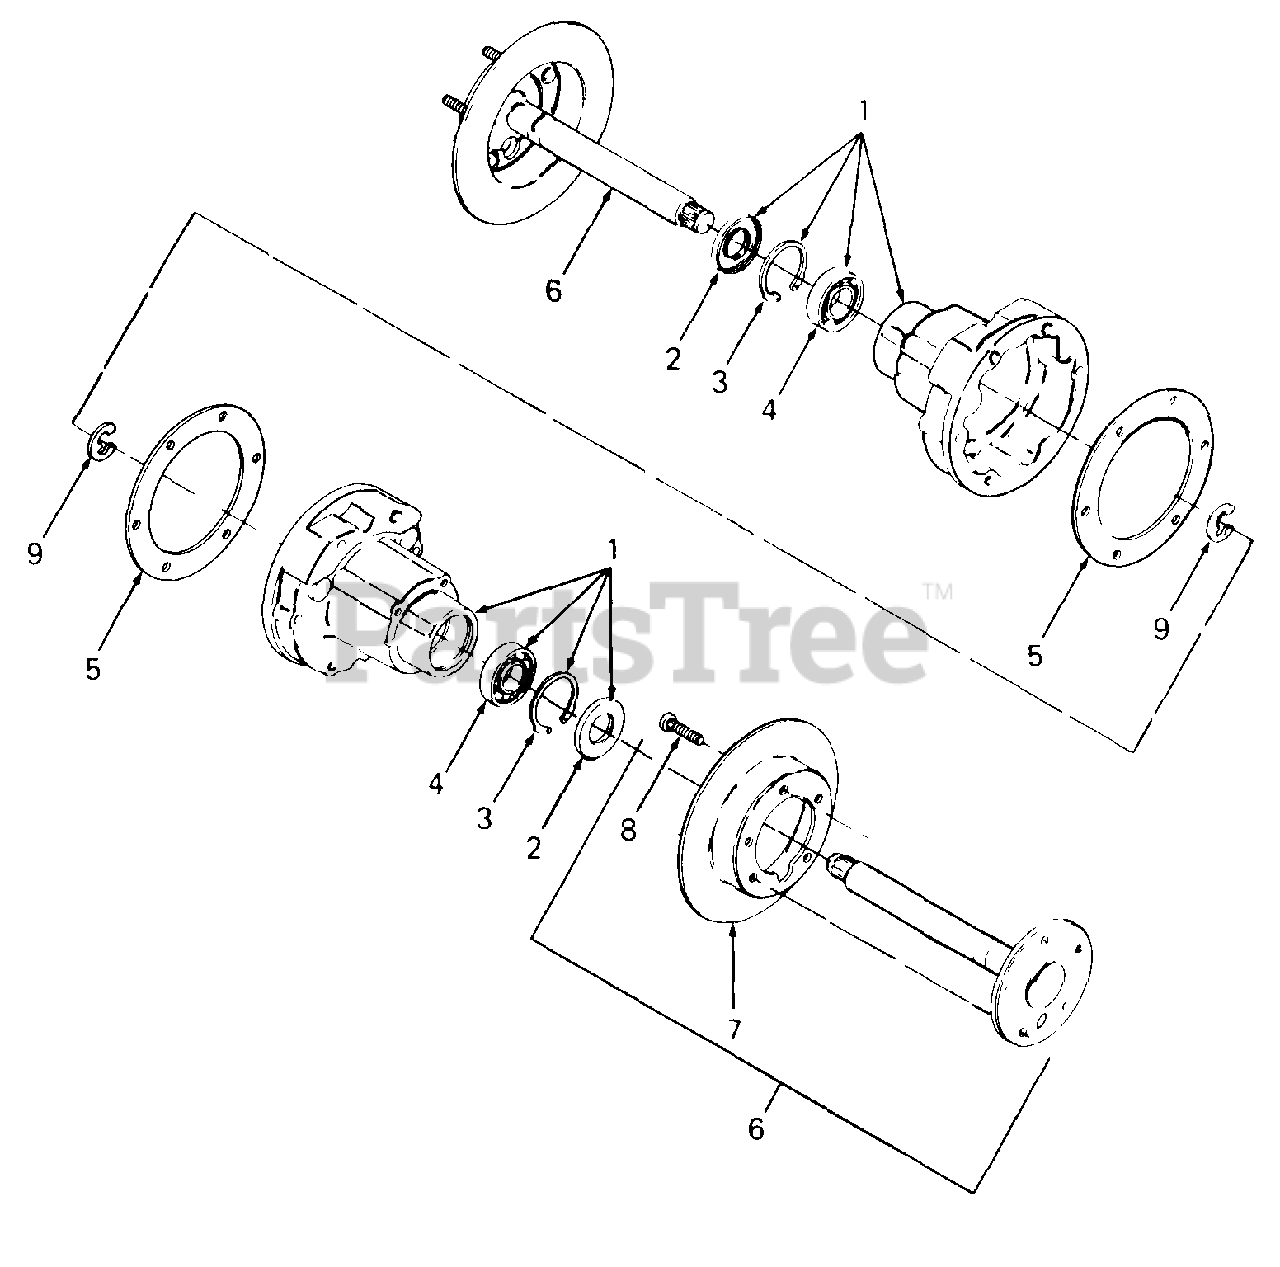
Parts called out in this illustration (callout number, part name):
1	Carrier Assy, Rear Axle
2	Seal, Oil
3	Ring, Retaining
4	Bearing, Ball
5	Gasket, Carrier
6	Axle Assy, Rear
7	Disc, Brake
8	Bolt, Lug
9	Retainer, E-Ring
